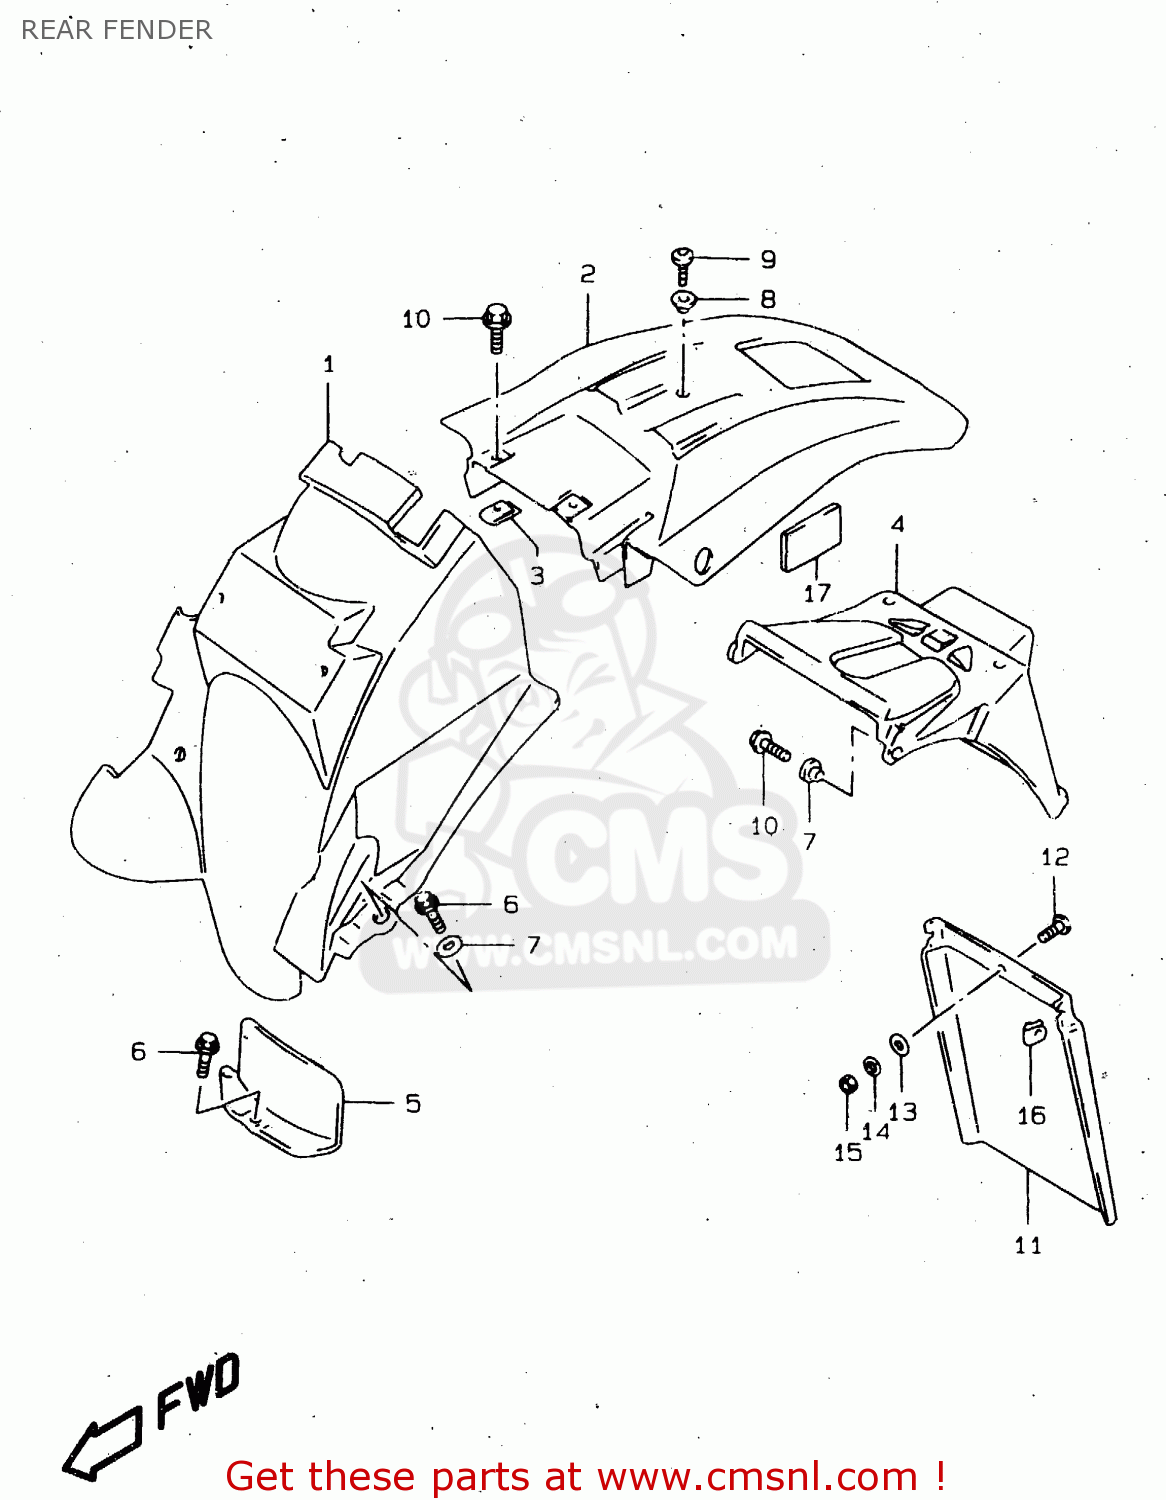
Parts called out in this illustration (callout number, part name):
1	BODY,RR FENDER FR
2	BODY, REAR FENDER REAR (WHITE)
3	PLATE,FRAME COVER
4	EXTENSION,RR FENDER
5	MUDGUARD,RR FENDER
6	BOLT(6X16)
7	WASHER
8	WASHER
9	SCREW(6X16)
10	BOLT
11	MUDGUARD,RR FENDER RR
12	SCREW
13	WASHER(5.5X16X1.2)
14	LOCK,WASHER
15	NUT
16	NUT
17	CUSHION
